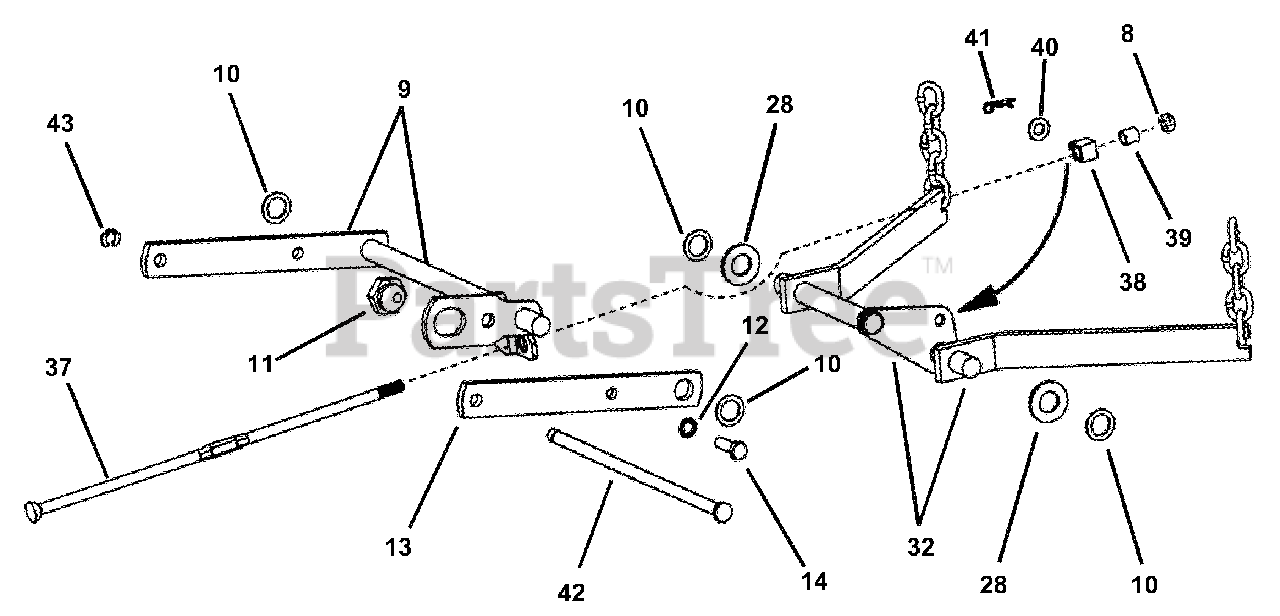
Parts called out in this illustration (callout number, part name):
8	NUT, 3/8-16 Hex Center Lock
9	ARM, Front Lift (weldment)
10	WASHER, 3/4"
11	ECCENTRIC, Leveling (3/8-24 thread)
12	WASHER, 3/8" Internal Tooth Lock
13	ARM, Front Lift
14	SCREW, 3/8-24 x 1-1/4" Hex Head Cap
28	WASHER, 25/32" Flat
32	ARM, Rear Lift (weldment)
37	ROD, Cutting Deck Timing
38	SWIVEL, Brake Link PM
39	SPACER, 25/64"
40	WASHER, 3/8"
41	HAIRPIN, #13
42	ROD, Deck Support
43	RING, 7/16" Snap
